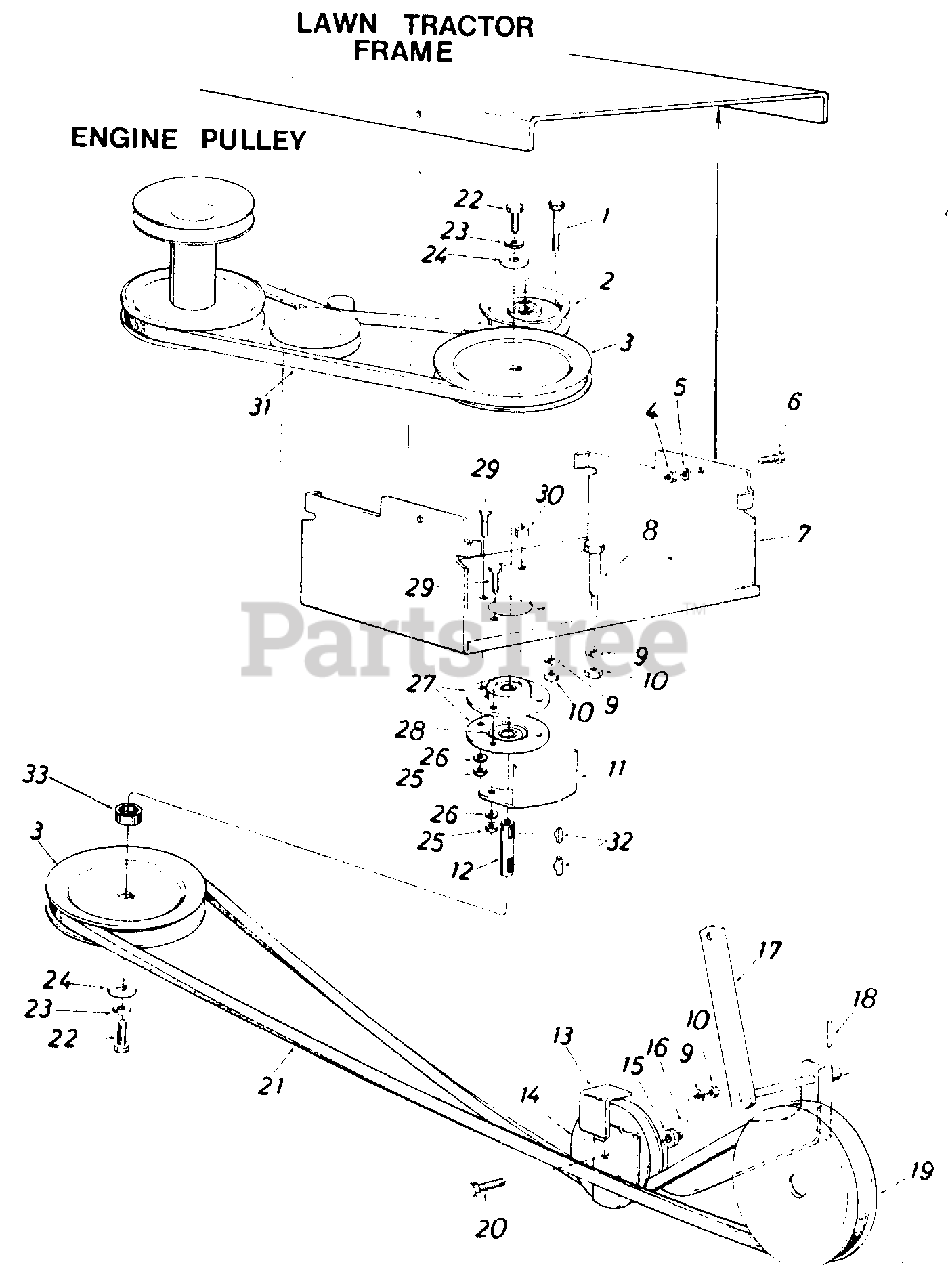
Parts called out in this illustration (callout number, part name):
1	Hex Bolt 3/8-16 x 2.00" Lg.*
2	Fl.ldler w/Flanges 3-3/4" O.D.
3	5/8" "V"-Pulley .790" I.D. x .650" O.D.
4	Hex Nut 3/8-24 Thd.*
5	L.Wash. 3/8" I.D. Heavy Duty
6	Hex Bolt 3/8-24 x .88" Lg.*
7	Carriage Bracket
8	Shoulder Bolt.498" Dia. x 1.64
9	L.Wash. 3/8" I.D.*
10	Hex Nut 3/8-16 Thd.*
13	Belt Separator Plate
14	Fl.ldler w/Flanges 3.25" O.D.
15	Fl.Wash. .406" I.D. x 1.25" O.D. x .164
18	Spring Pin Roll 3/16" Dia. x 1.50" Lg.
19	5/8" V-Pulley 1.50" I.D. x 6.50" O.D.
20	Hex Bolt 3/8-16 x 1.75" Lg.*.
21	"V"-Belt 1/2" x 95.0" Lg.
22	Hex Bolt5/16-18x .88" Lg. Spec.
23	L.Wash. 5/16" I.D.*
24	Fl.Wash. .344" I.D. x 1.125" O.D. x .125
25	Hex Nut 5/16-18 Thd.*
26	L.Wash. 5/16" I.D.*
27	Bearing Housing 1.85" I.D.
28	Ball Bearing .787" I.D. x 1.85" O.D.
29	Hex Sems Bolt 5/16-18 x .75"
30	Spacer
31	Belt 1/2" Wide x 52" Long
32	Hi-Pro Key 3/16" x 5/8"
33	Spacer-.80" I.D. x 1.0" O.D.
